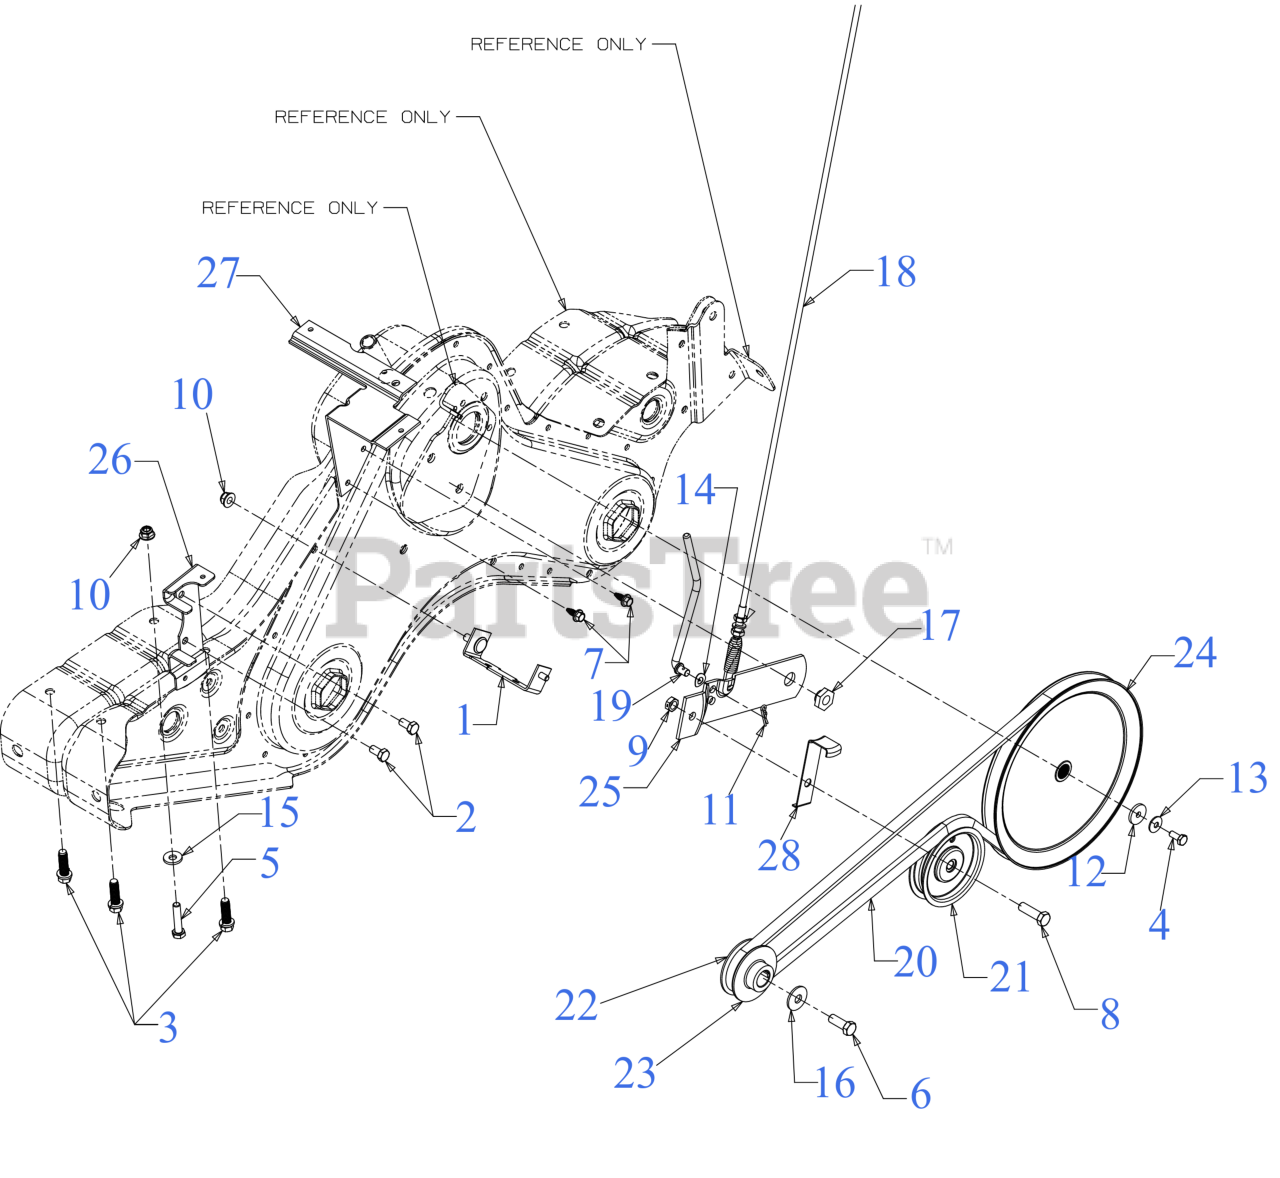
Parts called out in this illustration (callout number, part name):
2	HEX SCREW 5/16-24 x .62
3	SCREW 3/8-16 x 1.250
4	BOLT 1/4-28 x .625 GR8
5	SCREW 5/16-18 x 1.5 LG
6	SCREW 3/8-24 x 1.00 GR8
7	SCREW 1/4-20X.625
8	SCREW 3/8-16 x 1.25 GR5
9	JAM LOCK NUT
10	FLANGE LOCK NUT 5/16-18
11	COTTER PIN .072 DIA
12	FLAT WASHER
13	SPRING WASHER BELL
14	SHAKE PROOF WASHER
15	BELLVILLE WASHER .827 x .331 x .098
16	BELL WASHER
17	SHOULDER NUT
18	CLUTCH CABLE
19	IDLER PULLEY ROD
20	BELT 1/2 x 58.160"
21	IDLER PULLEY
22	ENGINE PULLEY INNER HALF
23	ENGINE PULLEY OUTER HALF
24	INPUT PULLEY
25	IDLER BRACKET
26	BELT KEEPER BRACKET
27	SHIFT COVER BRACKET
28	IDLER BELT KEEPER
